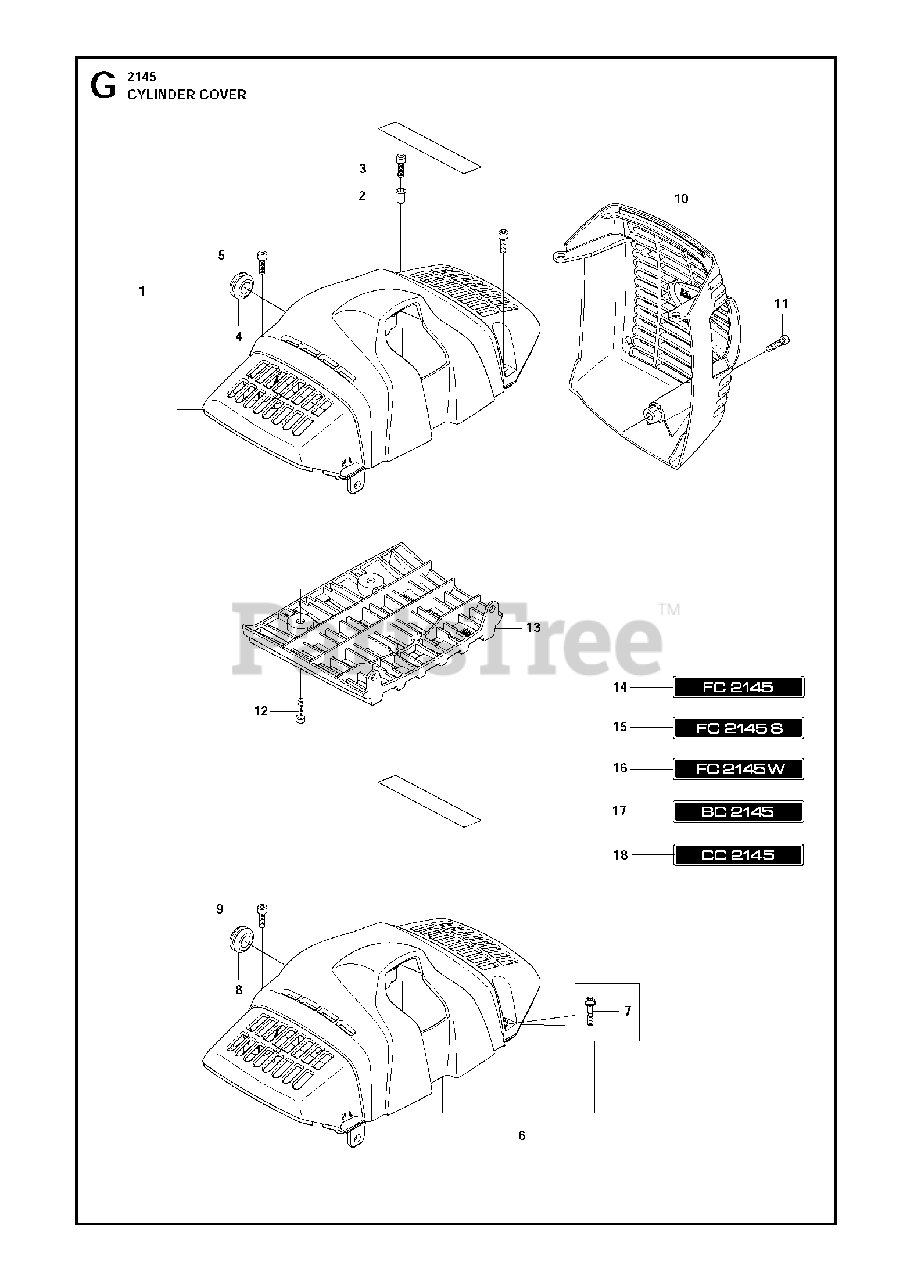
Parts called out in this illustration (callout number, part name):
3	SCREW IHSCFM
6	CYLINDER COVER ASSY
7	SCREW IHSCFMO
10	MUFFLER COVER
11	SCREW IHSCFM
12	SCREW IHSCFM
14	DECAL
15	DECAL
17	DECAL
